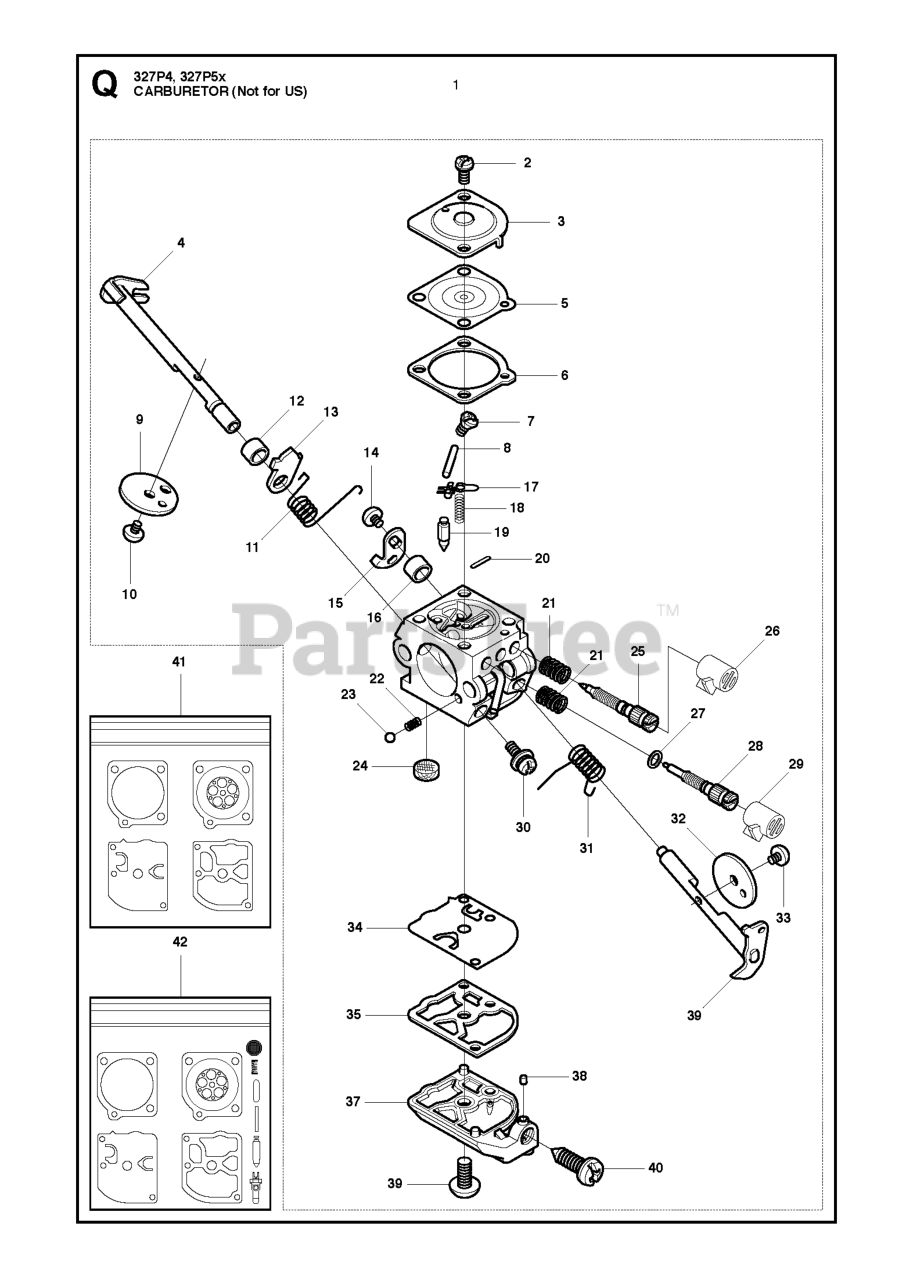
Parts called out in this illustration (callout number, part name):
1	CARBURETOR
8	PIN RETAINING SCREW
18	SPRING
19	INLET NEEDLE
21	SPRING
25	LOW SPEED NEEDLE
28	NEEDLE HIGH SPEED
31	SPRING THROTTLE
32	THROTTLE FLAP
34	PUMP DIAPHRAGM
41	GASKET KIT (ZAMA GND39)
42	CARBURETOR KIT (ZAMA RB69)
